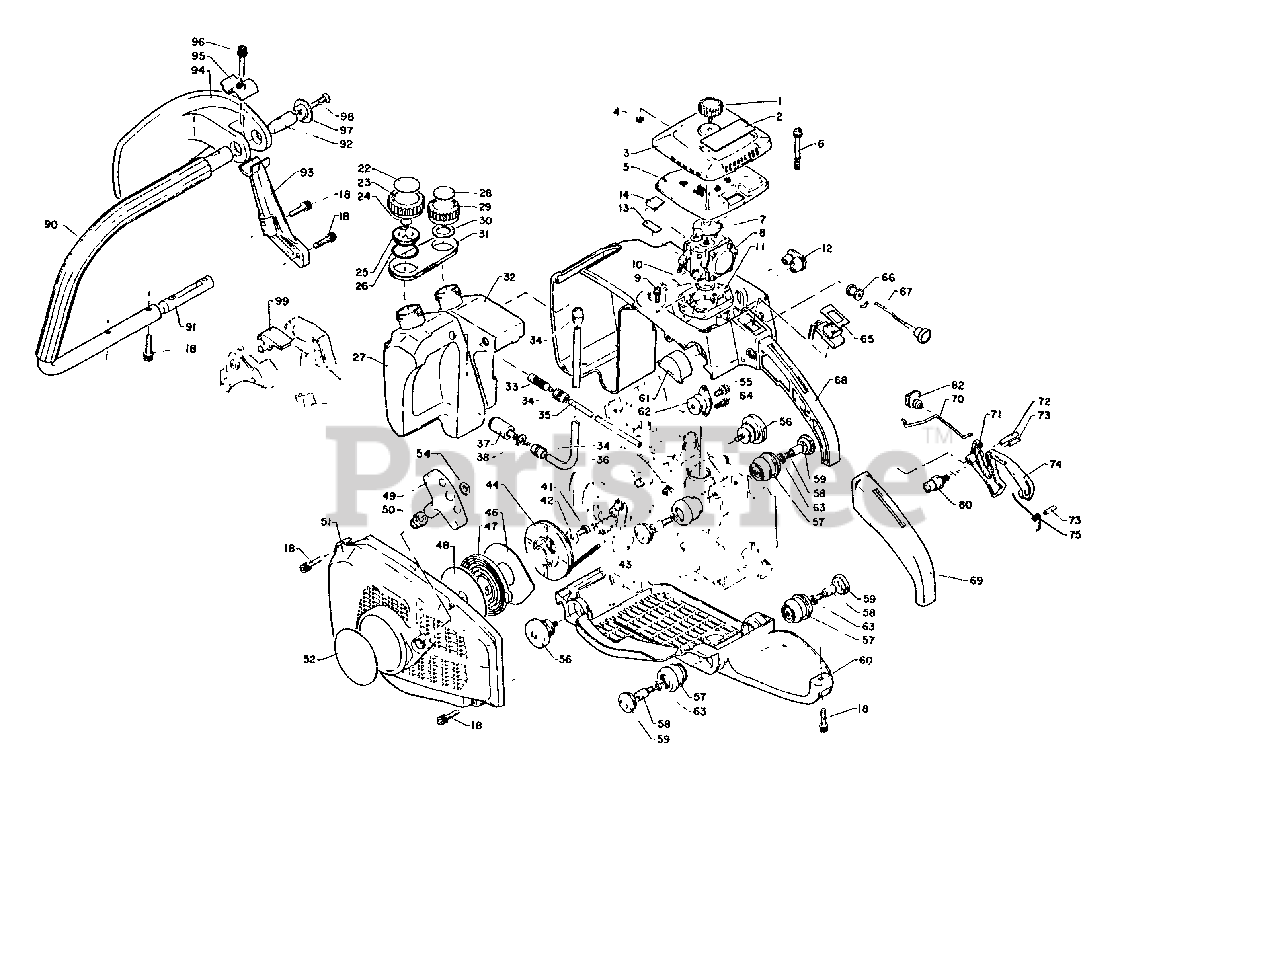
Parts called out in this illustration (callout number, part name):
1	THUMBSCREW
2	LABEL - CAUTION
3	COVER, AIR FILTER
4	E-RING 3
5	FILTER, AIR
6	SCREW 5×45
7	BRACKET, AIR FILTER
8	CARBURETOR
9	SCREW 4×12
10	HOLDER
11	ADAPTER
12	GROMMET
13	LABEL - OIL
18	BOLT 5×20
22	LABEL - FUEL MIX
23	CAP
24	VALVE, CHECK
25	HOLDER, CHECK VALVE
26	O-RING 22
27	TANK, FUEL
28	LABEL - OIL
29	CAP, OIL TANK
30	GASKET, CAP
31	CONNECTOR
32	TANK, OIL
33	FILTER, OIL
35	OIL PIPE KIT
36	FUEL PIPE KIT
37	FILTER, FUEL
38	WASHER 6.5×11.5×0.8
41	SCREW 5×10
42	WASHER 5.5×12×0.8
43	ROPE, STARTER
44	REEL, ROPE
46	PLATE, SIDE
47	SPRING, RECOIL
48	PLATE, STARTER
50	GUIDE, ROPE
51	CASE, STARTER
52	LABEL - ECHO
55	SCREW 5×10
56	CUSHION
58	SCREW
59	CAP, CUSHION
60	SUPPORT
61	COVER, CUSHION
63	WASHER, SPRING 5
64	SCREW 4×10
65	IGNITION SWITCH ASSY
66	GROMMET, CHOKE
67	ROD, CHOKE
68	HANDLE - REAR
69	GRIP, HANDLE
70	ROD, THROTTLE
71	TRIGGER, THROTTLE
72	PIN, SPRING 5×25
73	PIN, SPRING 4×13
74	LOCKOUT, THROTTLE
75	SPRING, LOCKOUT RETURN
80	LATCH, THROTTLE
90	HANDLE, FRONT
91	INSERT, FRONT HANDLE (L)
93	BRACKET, HANDLE - UPPER
94	GUARD
95	STOPPER
96	BOLT 5×30
97	RETAINER, GUARD
98	SCREW - 5×20
99	COVER
